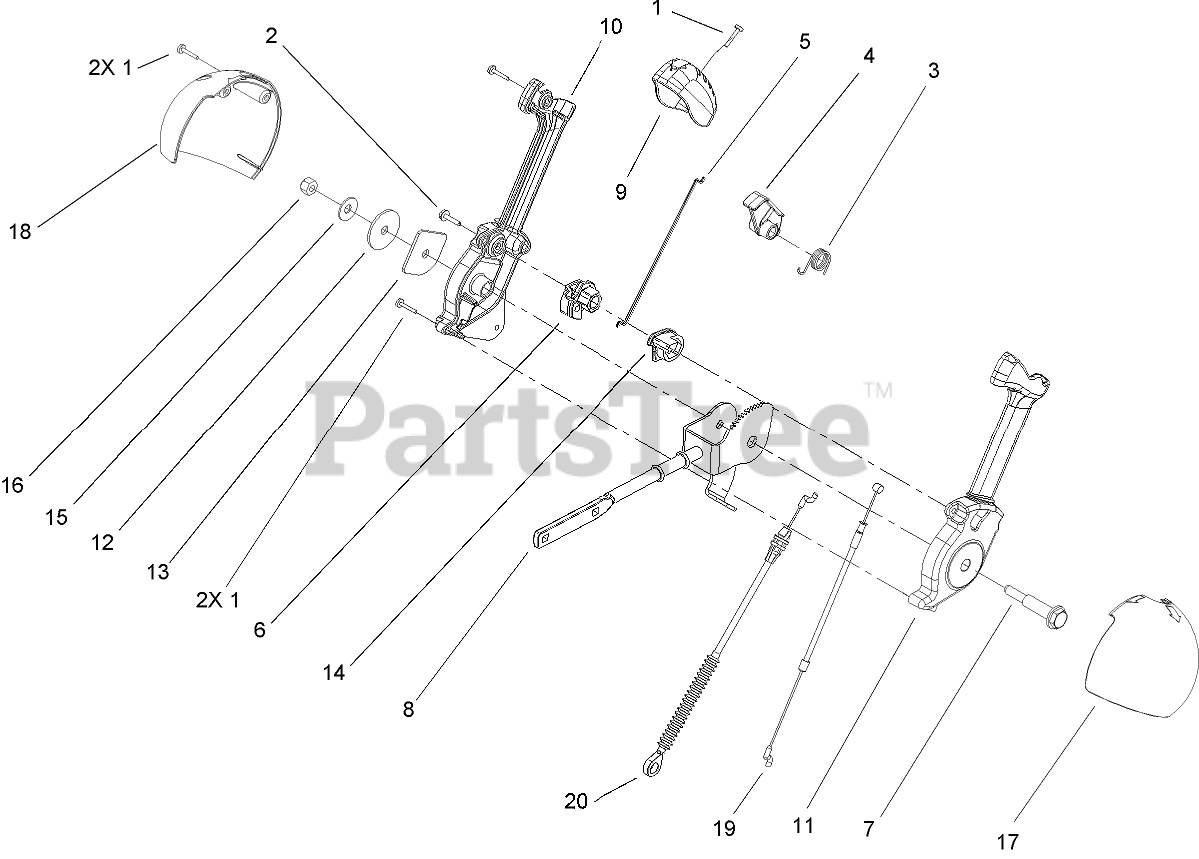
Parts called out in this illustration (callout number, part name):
1	SCREW-PPH
2	SCREW-HWH
3	SPRING-TORSION
4	TRIGGER-LATCH
5	LINK-LATCH
6	LEVER-CABLE, DEFLECTOR
7	SCREW-SHOULDER
8	ROD-CONTROL, CHUTE
9	CAP-LEVER
10	LEVER-CONTROL, CHUTE (RH)
11	LEVER-CONTROL, CHUTE (LH)
12	WASHER-NYLON
13	PLATE-FRICTION
14	PAWL-LATCH
15	WASHER-BELLEVILLE
16	NUT-LOCK, NI
17	COVER-LEVER, CHUTE (LH)
18	COVER-LEVER, CHUTE (RH)
19	CABLE-RELEASE, CHUTE
20	CABLE-CONTROL, DEFLECTOR
